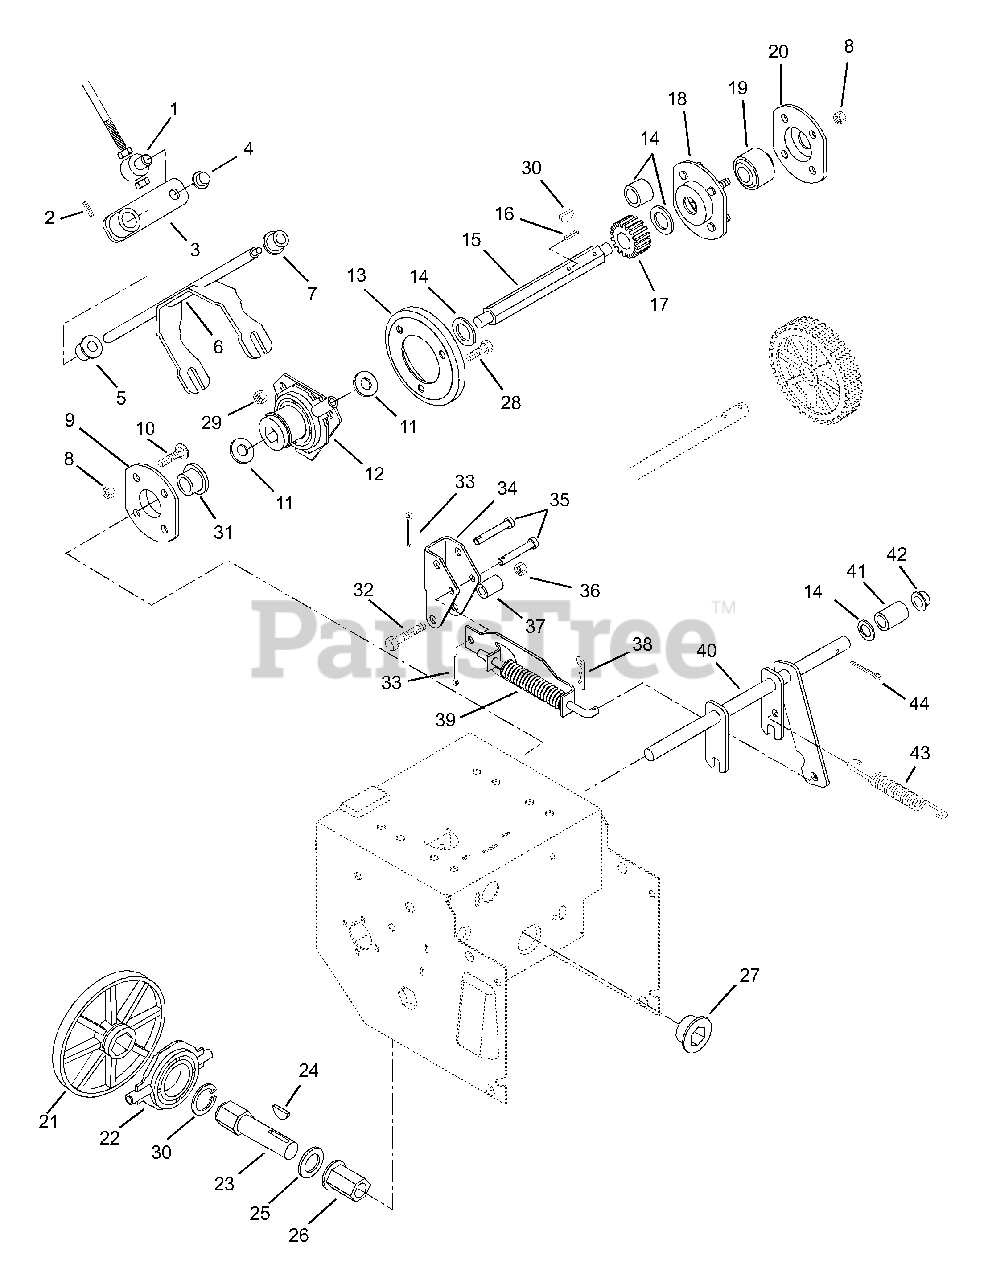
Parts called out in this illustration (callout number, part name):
2	PIN-ROLL .156X.88
3	ARM-SPEED CHANGE
4	CAP, 3/8 ROD YWZC
5	BSHG-FLG.500X.625X.312X.750NY
6	FORK-SPEED
7	BSHG-FLG .325X.444X.440X.560
8	NUT-LK-DUAL FACE 10-24 YWZC
9	BUSHING FLANGE
10	BLT-RDHDSQSHK #10-24X.38 GR2YW
11	WSHR-FL-STL .505X1.00X.062YWZC
12	SHIFT CARRIER
13	FRICTION DISC
14	@WSHR-FL-STL.531X1.06X.095YWZC
15	HEX SHAFT
16	PIN-ROLL .125X.88
18	BEARING FLANGE
19	BRG-BALL .500X1.38X.437
20	BEARING FLANGE
21	FRICTION PLATE
22	BEARING ASSEMBLY
23	HEX SHAFT
24	KEY-WDRF .188X.75X.313 SAE 9
25	WSHR, THRUST .625X1.125X.063
26	BSHG-FLG .625X.875X1.750X1.188
27	BSHG-FLG .875X1.25X.75X1.50HX
28	@BLT-HEX .25-20X.50 GR5 YWZC
29	@NUT-LK-CTR .25-20 YWZC
30	RG-RTNG-EXT 1.250X.050
31	BSHG-FLG .500X.750X.625X.937
32	@BLT-HEX .31-18X1.50 GR5 YWZC
33	@PIN-CTR .09X.50 EXTPRSQCT YWZ
34	BRACKET
35	PIN, CLEVIS .243/.248X1.50 YWZ
36	@NUT-LK-CTR .31-18 YWZC
37	SPACER -SPLIT .340X.490X1.02
38	PIN-HAIR INT .08X.18X1.18 YWZC
39	TRACTION CLUTCH ASSY
40	CLUTCH FORK
41	SPACER .504X.748X.321
42	CAP, .50 ROD YWZC
43	SG-TENS .063X.44X1.56
44	@PIN-CTR .12X1.00 EXTPRSQCT YZ
